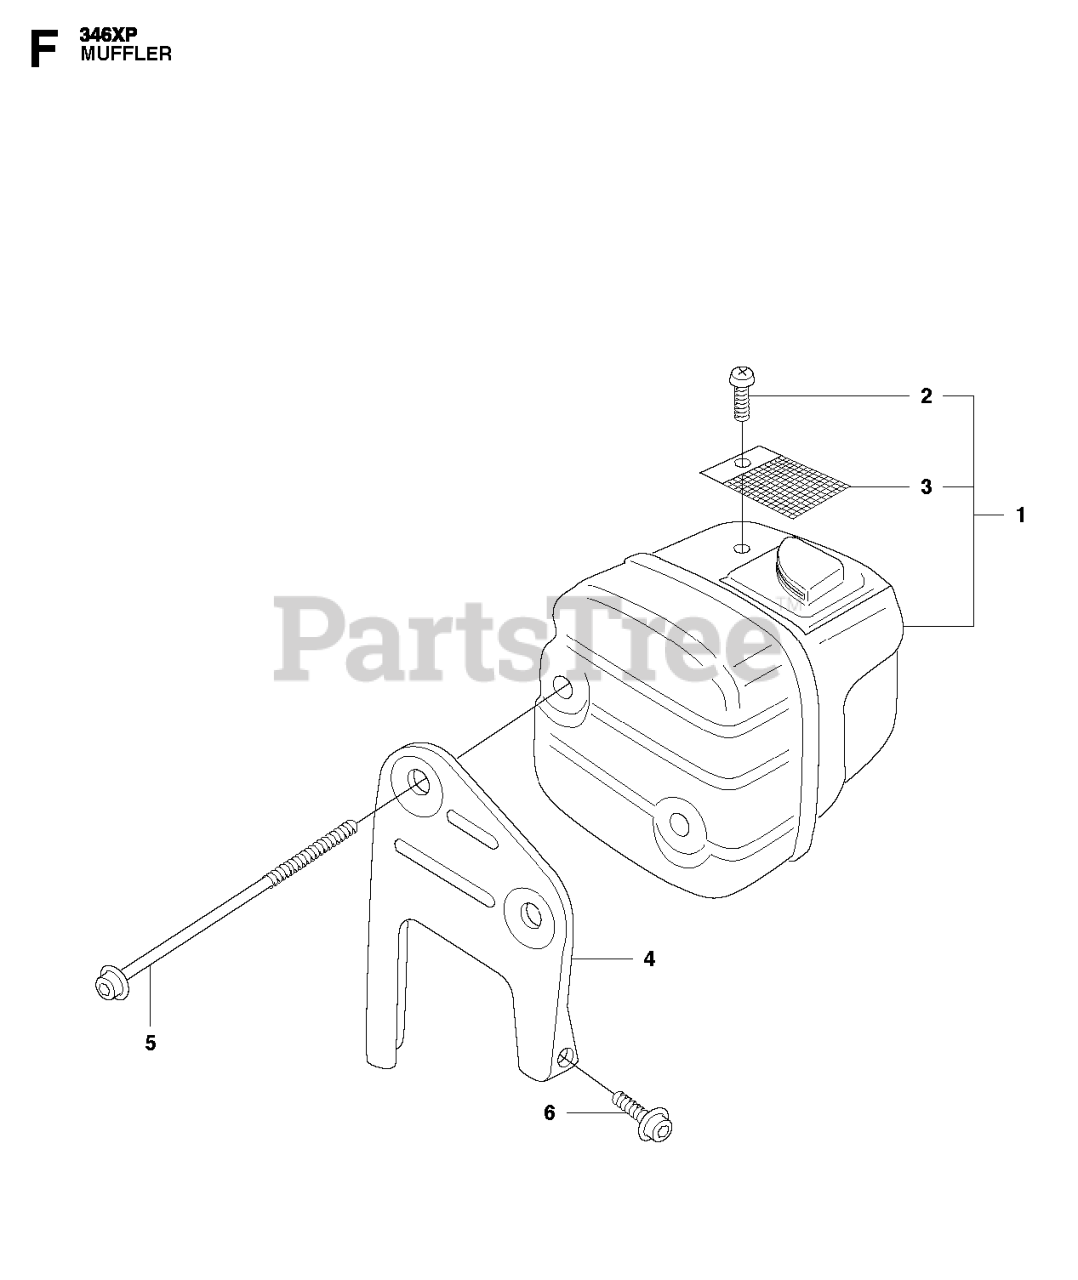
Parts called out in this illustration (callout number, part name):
1	MUFFLER
1	MUFFLER ASSY
2	SCREW
3	RP SCREEN
